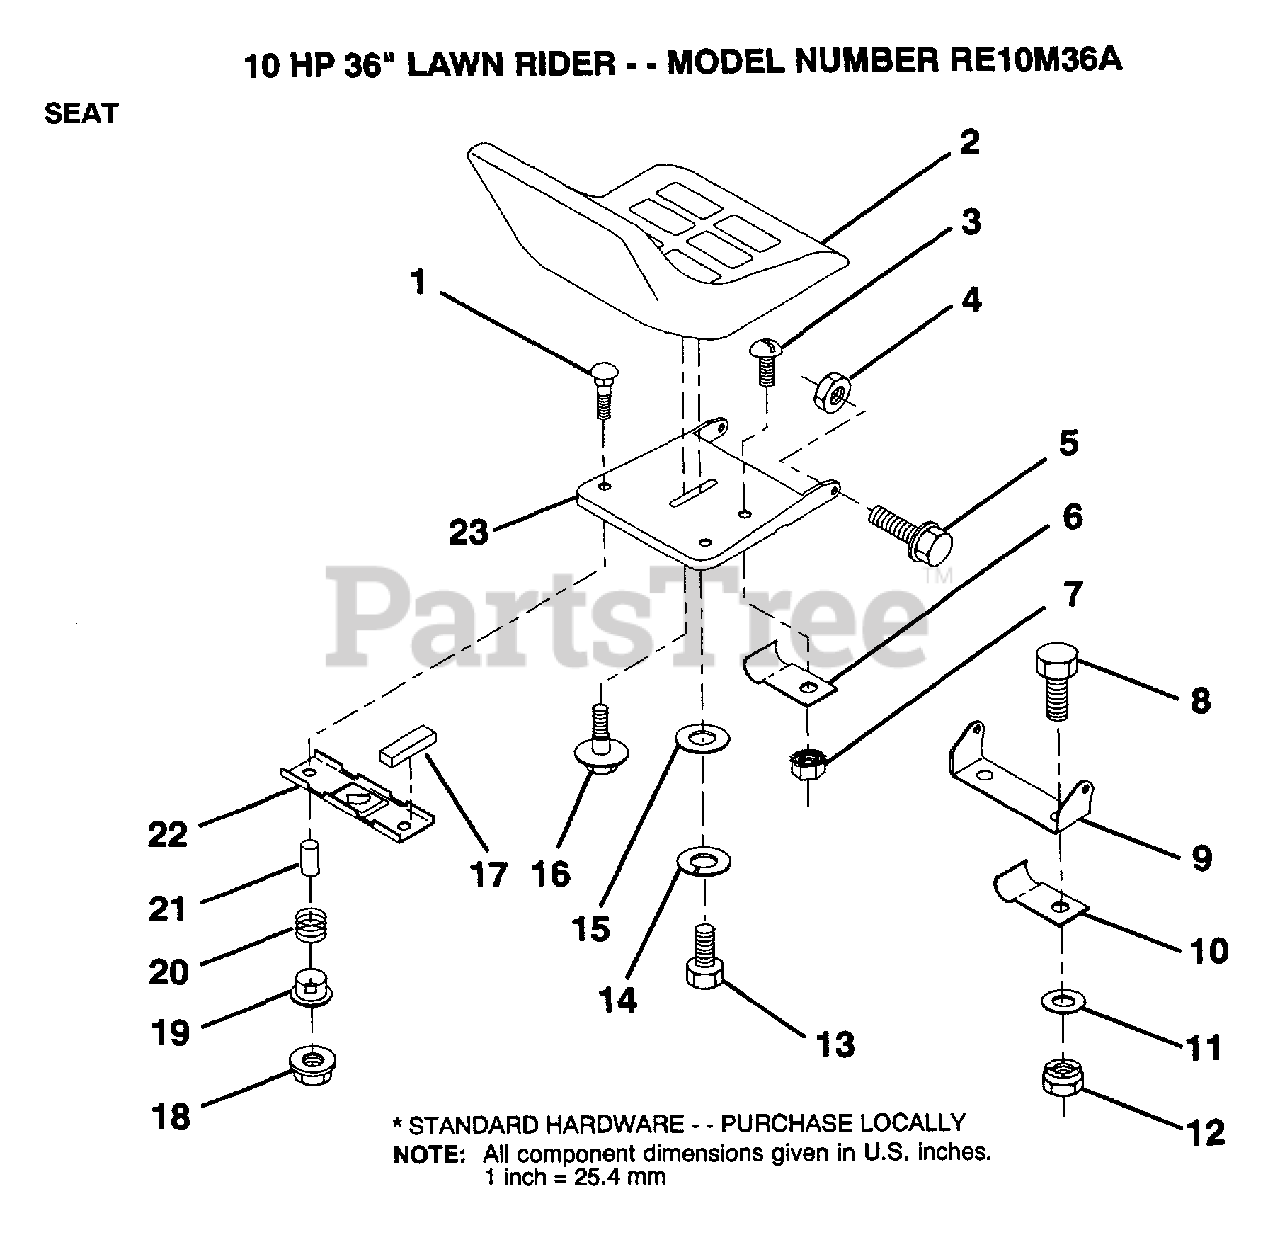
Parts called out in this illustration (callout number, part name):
7	"NUT,KEPS"
10	"CLIP,INSULATOR"
11	WASHER
13	BOLT
14	LOCKWASHER
15	WASHER
16	"BOLT,SHOULDER"
17	STRIP FORM
19	BUSHING
20	SPRING
21	SPACER SPLIT
22	BRKT SWITCH
